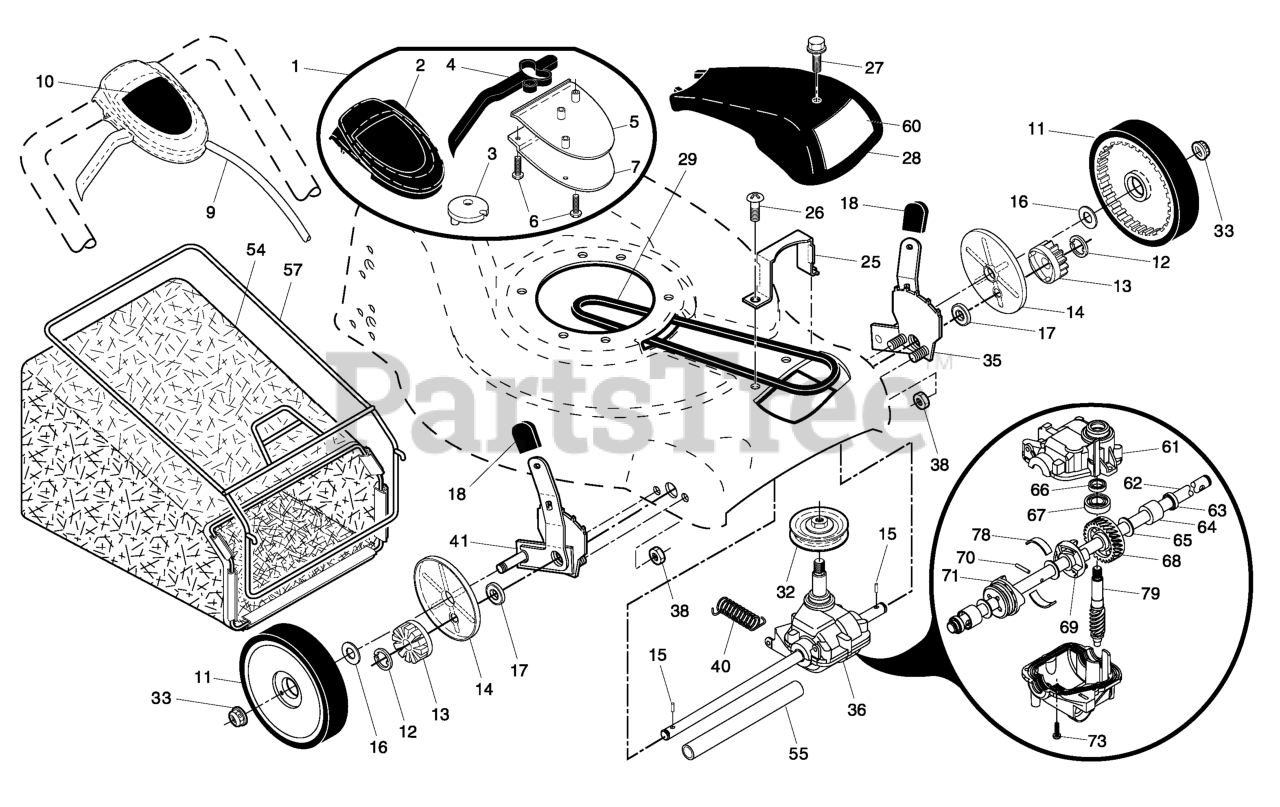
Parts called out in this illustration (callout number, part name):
1	DRIVE CONTROL ASSEMBLY (INCLUD
2	COVER TOP AUTO WALK CONTROL
3	PULLEY
4	LEVER, AUTOWALK DRIVE CONTROL
5	COVER BOTTOM AUTO WLK CONTROL
6	SCREW, PHILLIPS HEAD 10 X 5/8
7	BRACKET.DRIVE.CONTROL.MOUNT.BL
9	CABLE ASSEMBLY, DRIVE
10	DECAL, DRIVE
11	WHEEL.8X1.75.H3SPK.RAD3.GY.BU3
12	E-RING 7/16 RE
13	PINION.14.TEETH.FGD
14	COVER.DUST.WHEEL
15	PAWL.DRIVE
16	WASHER FLUT
17	BEARING ASM
18	SELECTOR KNOB
25	BELT KEEPER
27	SCREW, HEX HD TAPPING #10-24 1
28	COVER.DR.21.FWGD/B&S.GRAY
29	BELT.DRIVE.FG
32	RP PULLEY.DRIVE.EZ
33	HEX FLANGE LOCKNT
35	WHEEL ADJ KIT LH
36	TRANSMISSION.21.FGD.HT.VST
38	LOCKNUT.NYLOC.1/4-20
41	WHEEL ADJ KIT RH
54	GBAG.34710247.SILVER.H
55	DRIVESHAFT COVER
57	FRAME, GRASSBAG
60	DECAL DRIVE COVER
61	CASE.UPPER.00254(SERVICE)
62	SHAFT OUTPUT (12289)
63	SEAL.OUTPUT.SHAFT
66	SEAL INPUT SHAFT
68	GEAR 28 TEETH 36208
69	FIXED DOG CLUTCH
70	PIN.3.50.33733
71	MOVEABLE DOG CLUTCH
74	CASE.BOTTOM.
78	SPRING LEAF
79	SHAFT WORM
